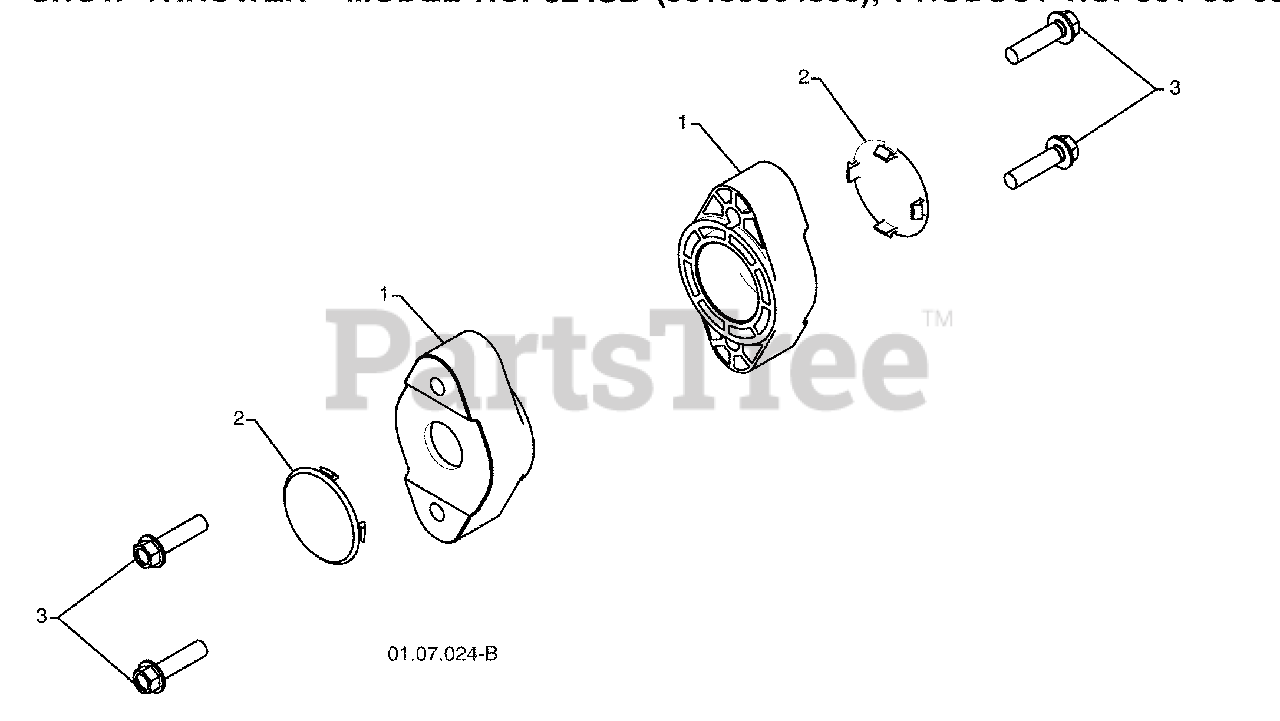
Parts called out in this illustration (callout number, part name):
1	AUGER BEARING
2	BEARING PLUG
3	SCREW 5/16-18 X 1.00
